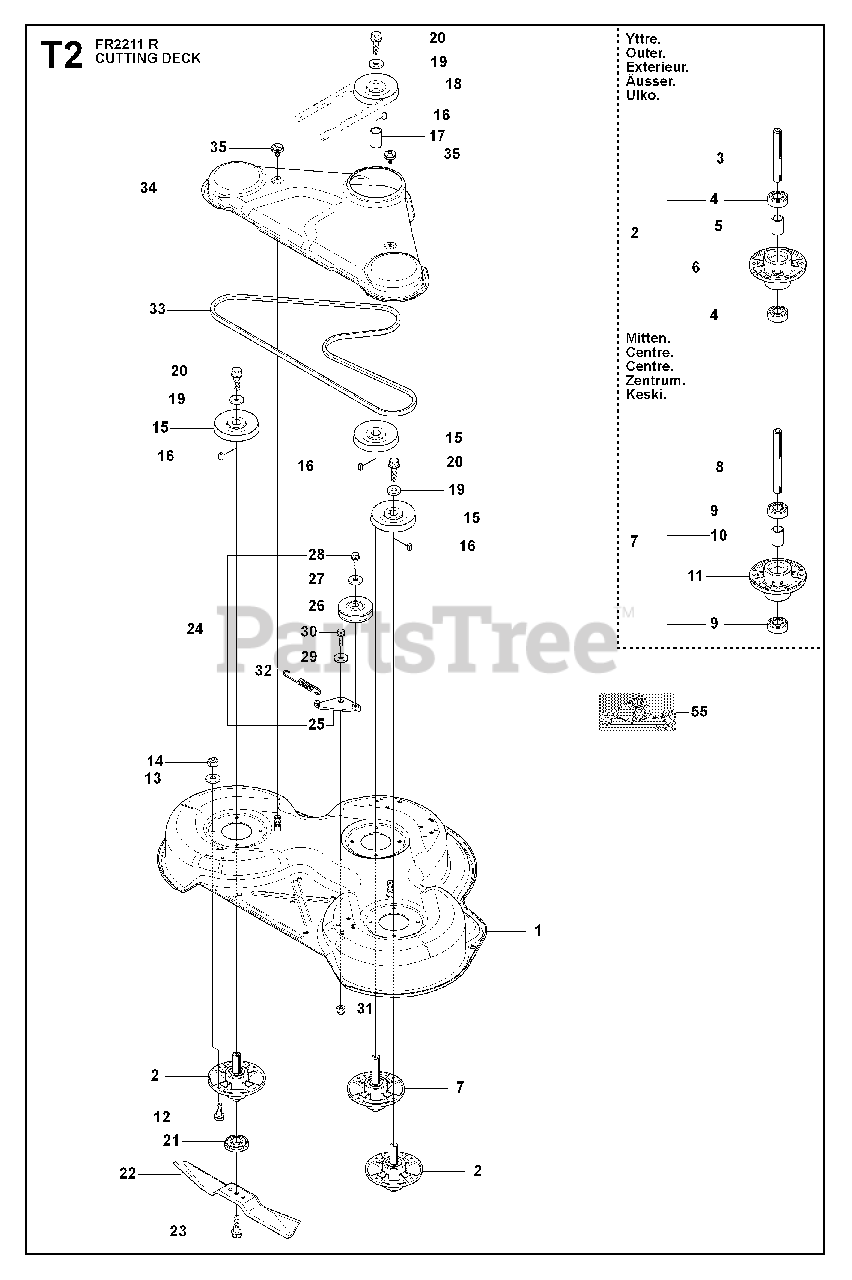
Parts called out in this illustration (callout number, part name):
2	RP SPINDLE ASSY
6	BEARING HOUSING
11	BEARING HOUSING
13	WASHER BRB 8.4X17
14	LOCKNUT M8
26	PULLEY
29	WASHER
31	LOCKNUT M8
